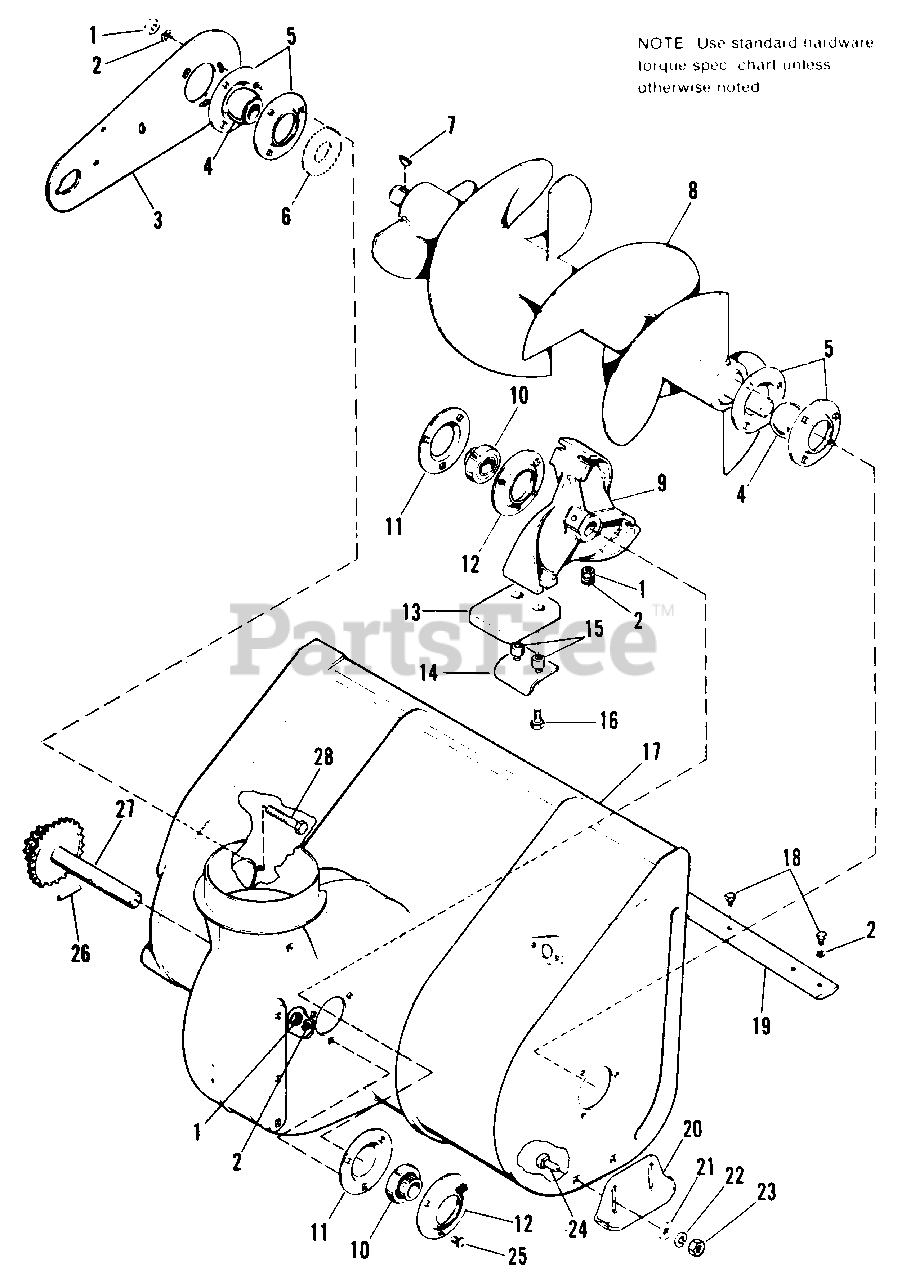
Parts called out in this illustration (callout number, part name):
1	NUT, Hex, Full, 5/16-18
2	LOCKWASHER, 5/16 (Qty. 24 on 1690379 & 1690380 Only)
3	PLATE, Side
4	BEARING ASSY., Ball
5	BEARING, Flange
6	PLATE (1690442 Only)
7	KEY, Woodruff, #15
8	ROTOR ASSY.,
8	ROTOR ASSY., (1690442 Only)
10	BEARING, Cartridge
11	FLANGE, Bearing
12	FLANGE, Bearing
13	BLADE, Impeller
14	PLATE, Backup
16	SCREW, Hex, Whizlock, Flange, 5/16-18 x 1-1/2
17	BODY ASSY.
17	BODY ASSY., (1690442 Only)
18	CAPSCREW, Hex Hd., 5/16-18 x 1/2 (Qty. 6 used on 1690379 & 1690380)
19	SCRAPER, Body
19	SCRAPER, Body (1690442 Only)
21	WASHER, Plain, 3/8
22	LOCKWASHER, 3/8
23	NUT, Hex, Full, 3/8-16
24	BOLT, Carriage, 3/8-16 x 3/4
25	BOLT, Carriage, 5/16-18 x 5/8
26	PIN, Spring, 5/16 x 1-7/8
27	SPROCKET & SHAFT ASSY.
28	CAPSCREW, Hex, Hd., 5/16-18 x 3/4
